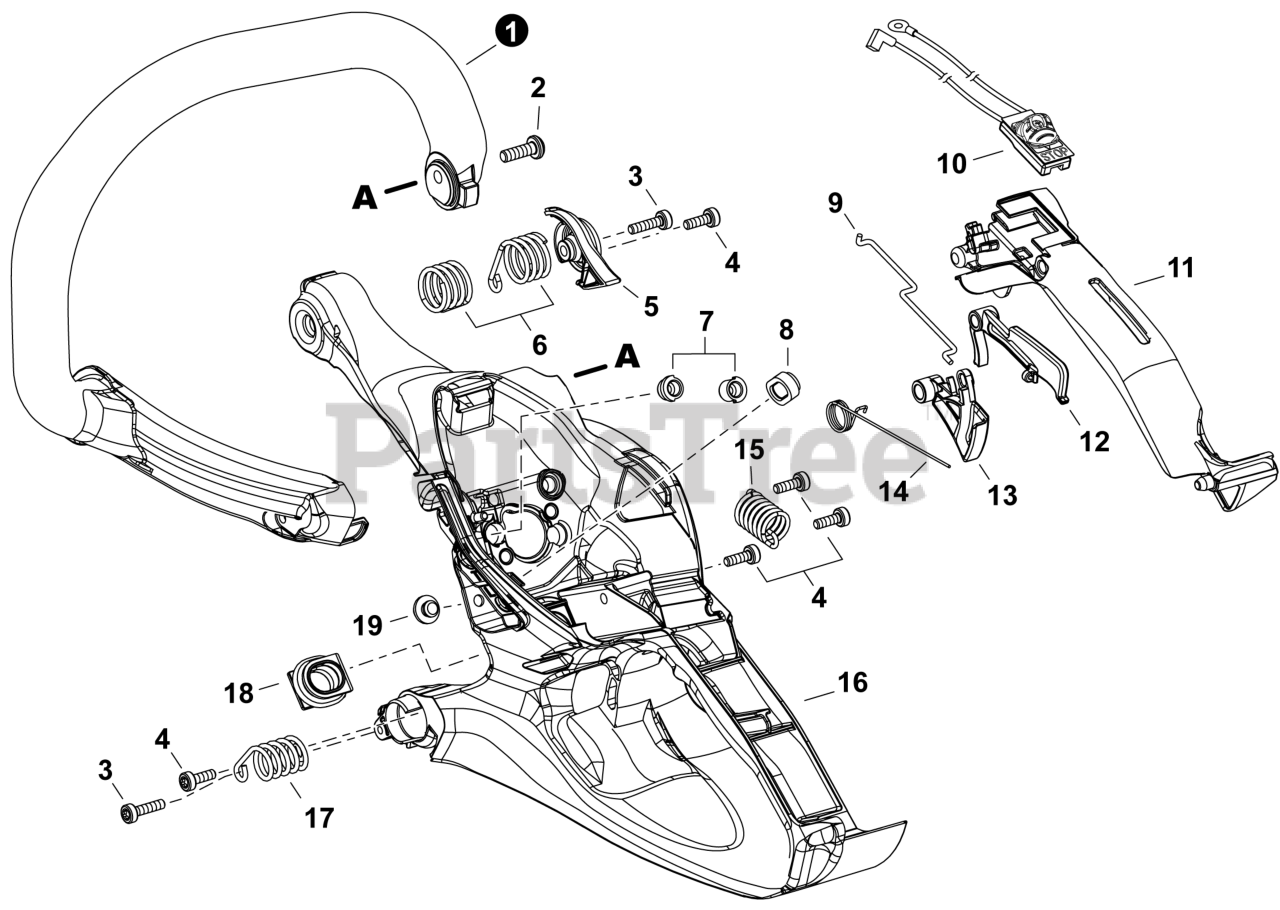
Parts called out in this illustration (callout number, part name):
1	HANDLE, FRONT
2	BOLT, TORX 5x16
3	BOLT, TORX 4x16
4	BOLT, TORX 4x12
5	HOLDER, SPRING
6	SPRING, COMPRESSION
8	GROMMET, NEEDLE
9	ROD, THROTTLE
10	SWITCH, ON-OFF
11	COVER, HANDLE
12	LOCKOUT, THROTTLE
13	TRIGGER, THROTTLE
14	SPRING, TORSION
15	SPRING, COMPRESSION
16	HANDLE, REAR
17	SPRING, COMPRESSION
18	PIPE, INTAKE
19	CUSHION
